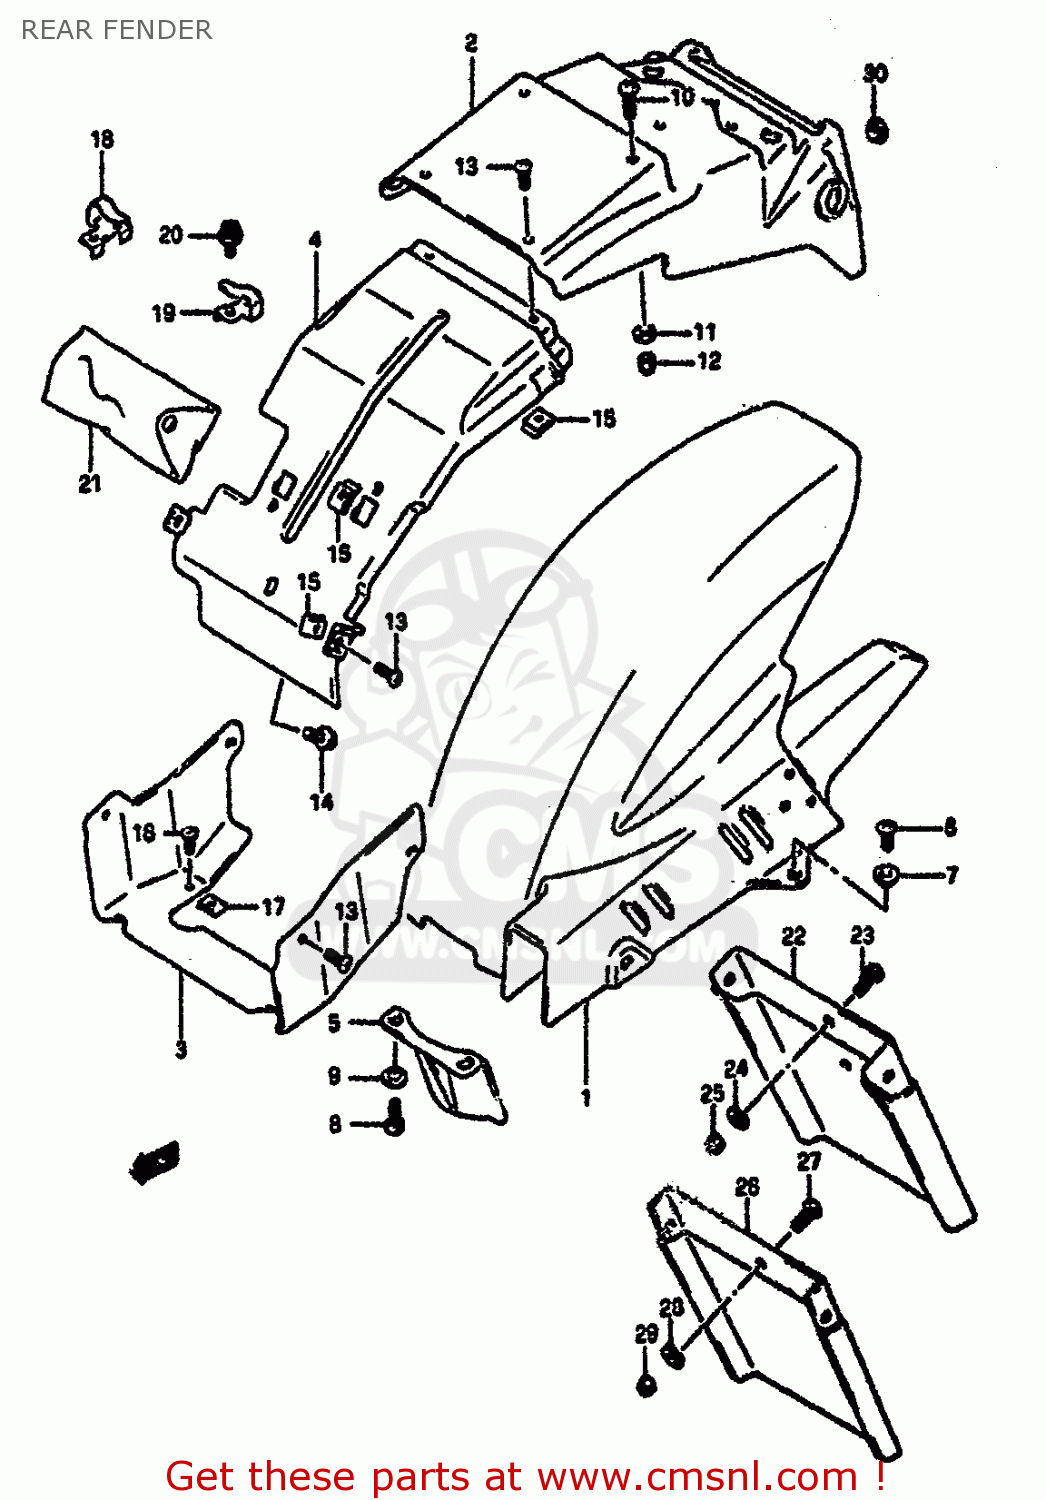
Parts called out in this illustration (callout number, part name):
1	FENDER,RR LWR
2	FENDER,RR UPR
3	FENDER,REAR
4	FENDER,RR UPR FR NO.2
5	GUARD,RR UNIT MUD
6	SCREW
7	WASHER
8	SCREW
9	WASHER,LOCK
10	SCREW
11	WASHER
12	NUT
13	SCREW, FRONT & REAR
14	BOLT
15	NUT,HEADLAMP HOUSING,UPPER
16	SCREW, FRONT & REAR
17	NUT,HEADLAMP HOUSING,UPPER
18	HOLDER,HELMET,R
19	HOLDER,HELMET,L
20	BOLT
21	TOOL SET
22	EXTENSION, REAR FENDER
23	SCREW
24	WASHER
25	NUT
26	MUD GUARD
27	SCREW
28	WASHER
29	NUT
30	CAP(OD:16)
